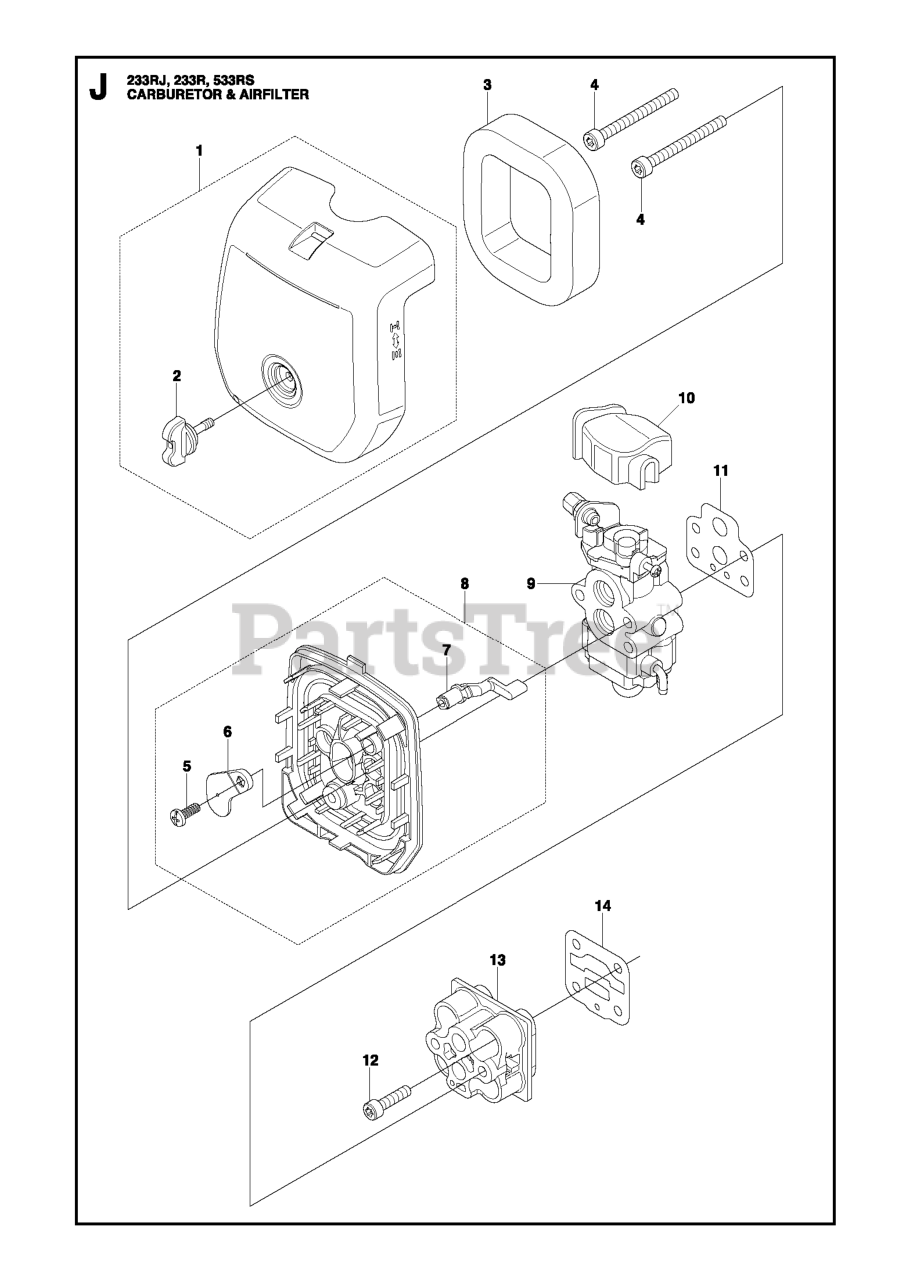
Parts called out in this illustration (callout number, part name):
6	PLATE.CHOKE
7	LEVER CHOKE
11	GASKET, CARB (RPLS T155113131)
12	BOLT, TORX
14	GASKET, INSULATOR
